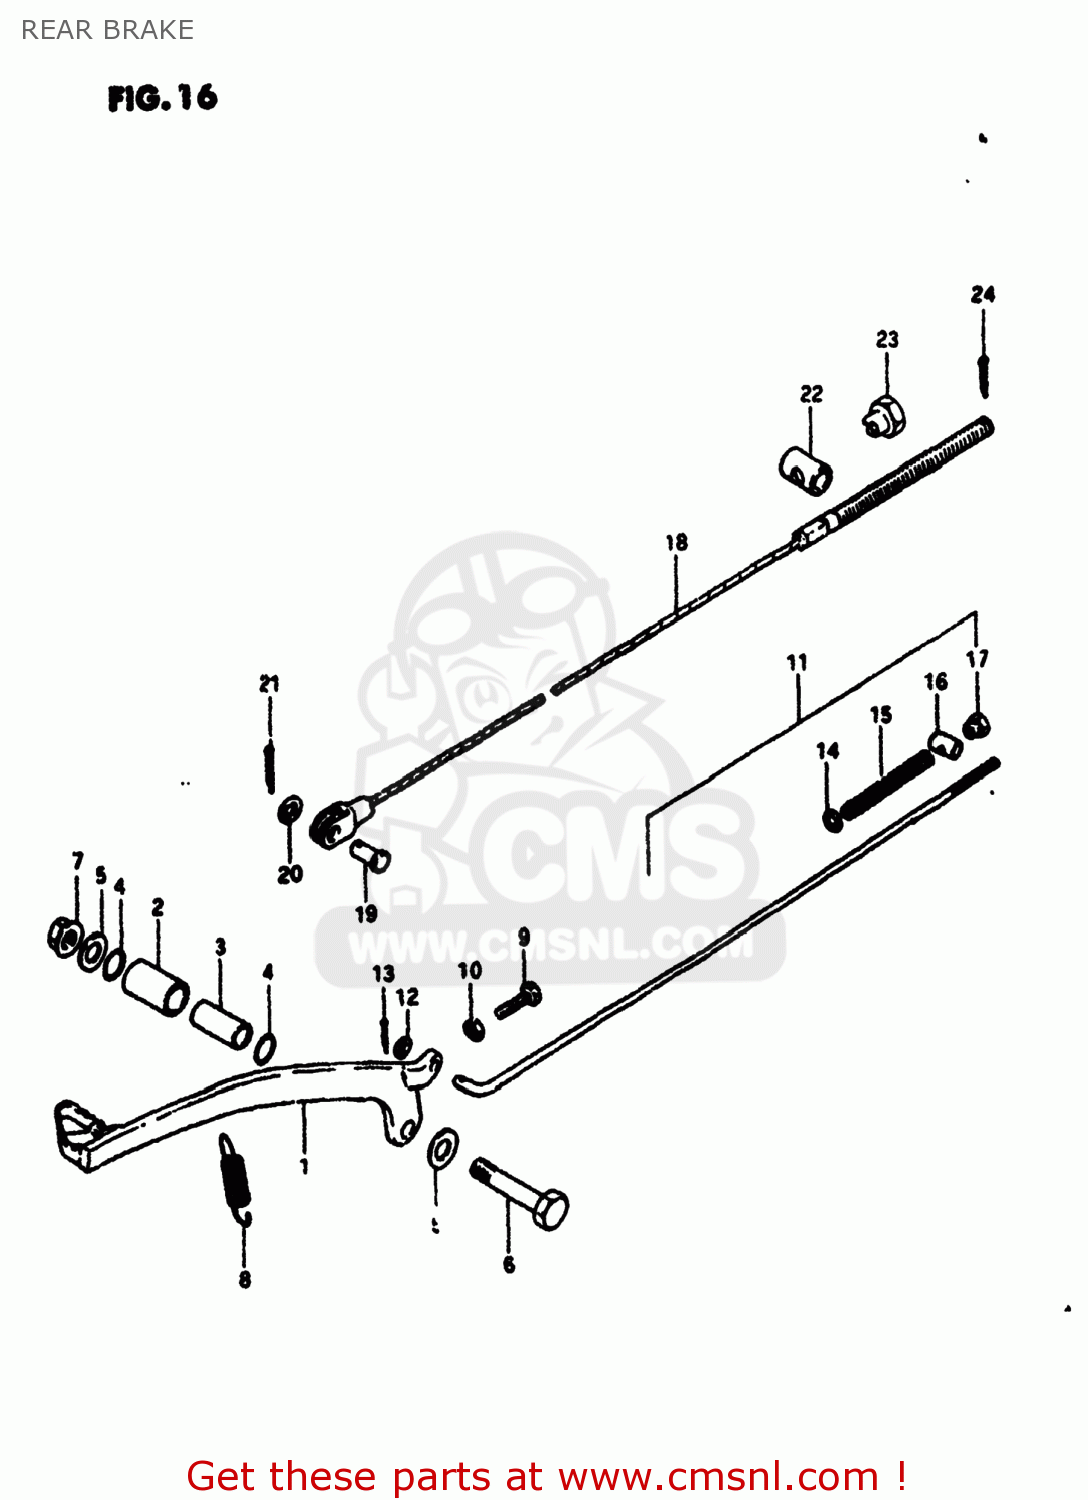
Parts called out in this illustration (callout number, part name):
1	PEDAL,BRAKE
2	BUSH
3	SPACER(10X14X32.2)
4	O RING(D:1.5,ID:13.8)
5	WASHER
6	BOLT
7	NUT
8	SPRING
9	BOLT(6X23)
10	NUT
11	ROD ASSEMBLY,REAR BRAKE
12	WASHER
13	PIN 20X20
14	WASHER
15	SPRING
16	PIN
17	NUT
18	CABLE,RR BRAKE
19	PIN(L:17.5)
20	WASHER
21	PIN 20X20
22	PIN
23	NUT
24	PIN
